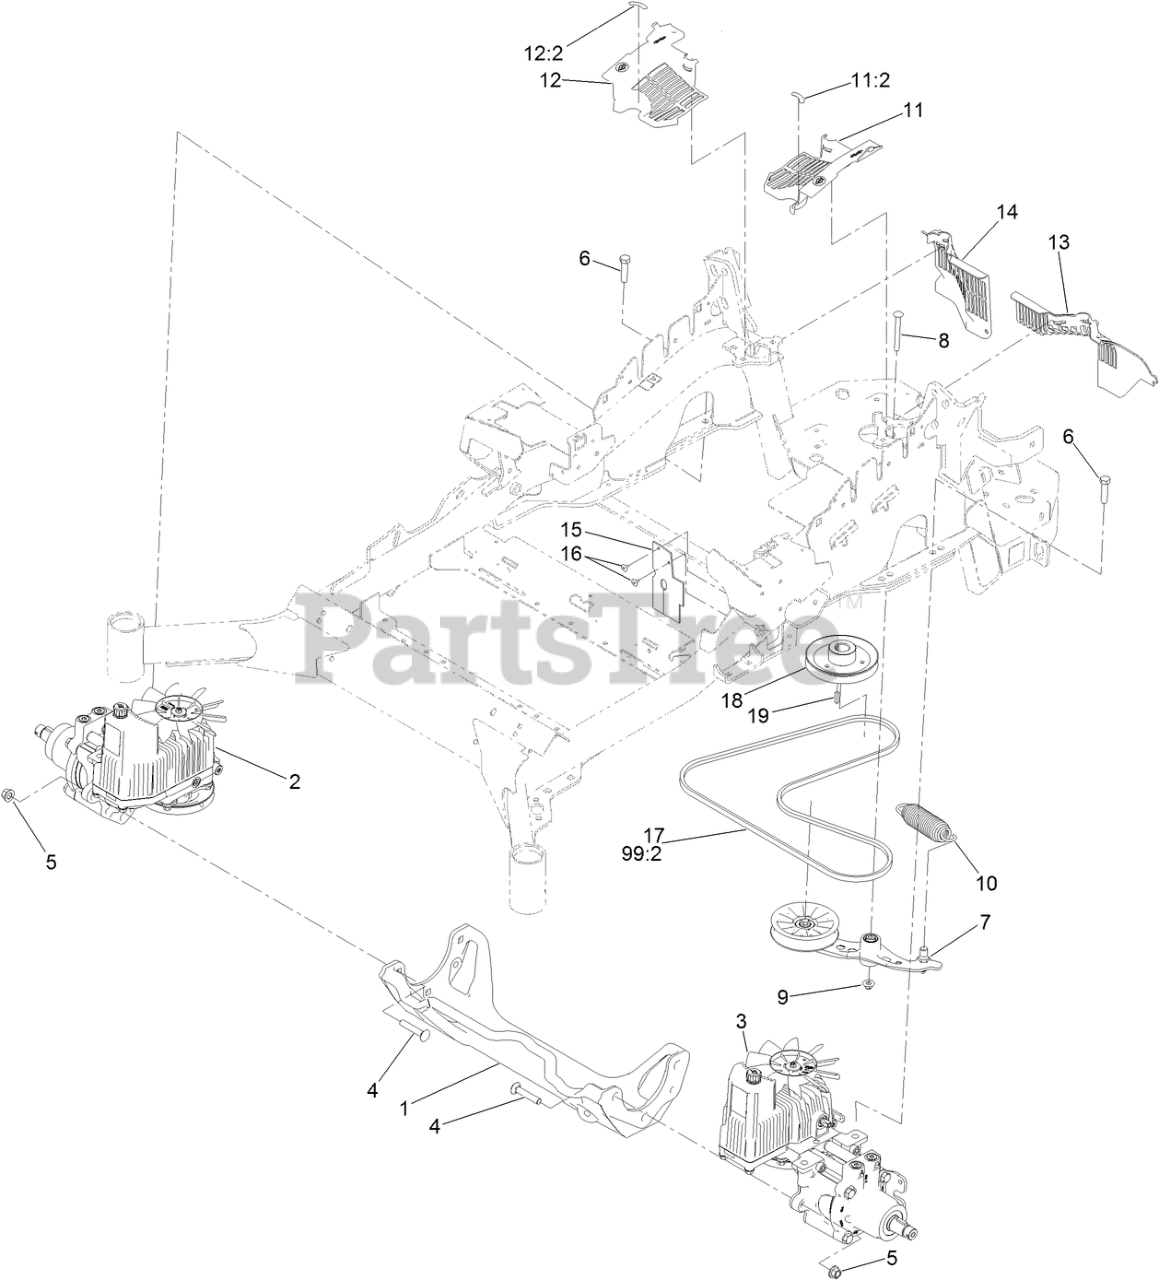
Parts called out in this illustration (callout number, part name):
1	CRADLE-HYDRO
2	HYDRO-RH
3	HYDRO-LH
4	SCREW-CARR
5	NUT-LOCK
6	SCREW-HH
7	PUMP IDLER ASM
8	BOLT-SHOULDER, CARRIAGE
9	NUT-FLANGE, NI
10	SPRING-EXTENSION
11	LH HYDRO GUARD ASM
11:2	DECAL-OIL, HYDRO
12	RH HYDRO GUARD ASM
12:2	DECAL-OIL, HYDRO
13	GUARD-HYDRO REAR, LH TRIM
14	GUARD-HYDRO, REAR (RH)
15	DEFLECTOR-AIR FLOW
16	RIVET-POP
17	BELT-V
18	SHEAVE
99:2	BELT
